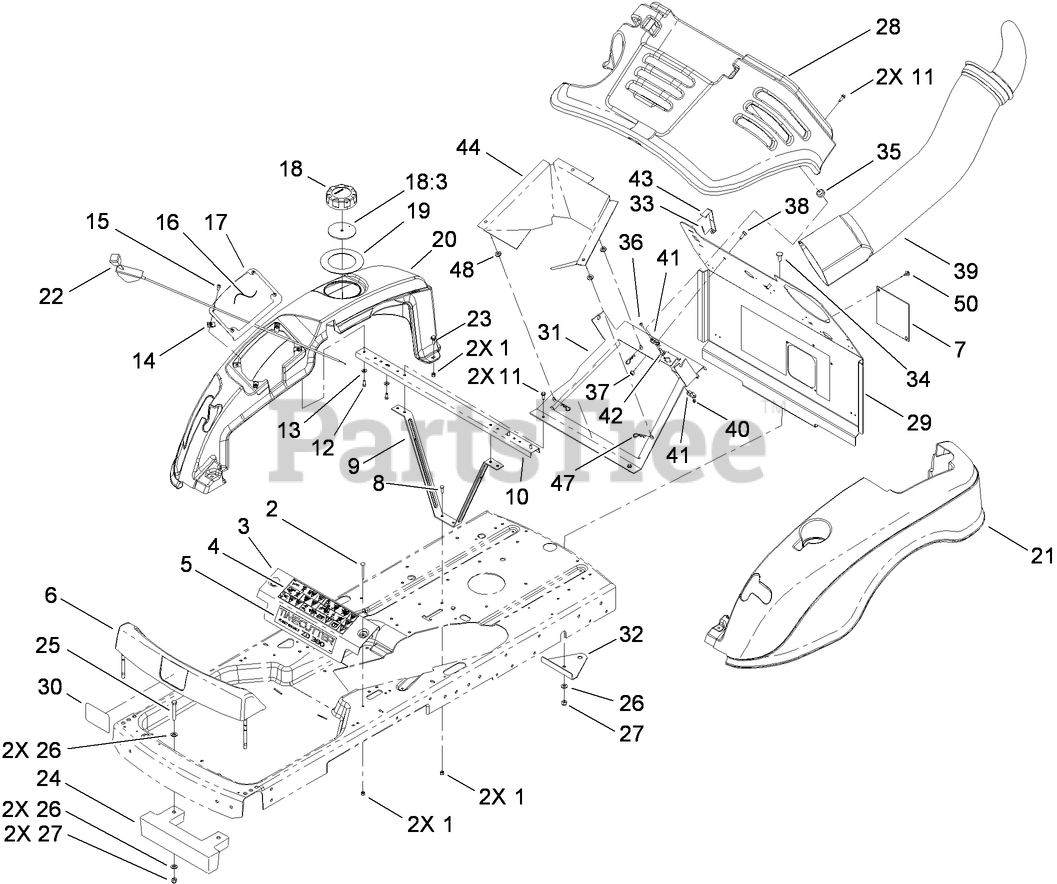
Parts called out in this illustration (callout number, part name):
1	NUT-LOCK, NI
2	SCREW-CARR
3	BRACKET-SUPPORT, FRONT
4	DECAL-DANGER
6	FOOTREST ASM
7	ACCESS DOOR ASM
8	SCREW-HH
9	BRACE ASM
10	CHANNEL-CROSS
11	SCREW-HWH, THREAD ROLL
12	SCREW-PLASTITE
13	WASHER-FLAT
15	SCREW-PRH
16	DECAL-CONTROL
17	PANEL-CONTROL
18	GAS CAP ASM
18:3	GASKET-CAP, GAS
19	SEAL-RUBBER
20	COVER-SIDE, RH
21	COVER-SIDE, LH
22	CABLE-THROTTLE
23	SCREW-SHOULDER
24	WEIGHT-BAGGER
25	SCREW-HH
26	WASHER-FLAT
27	NUT-LOCK, NI
28	COVER-ENGINE
29	SHIELD-HEAT, BAG
31	OFFSET HINGE ASM
32	HITCH-TRAILER
33	PIN-COTTER
34	SCREW-CARR
35	GROMMET
36	SCREW-HSBH
37	NUT-LOCK, NI
38	SCREW-HH
39	TUBE-DISCHARGE
40	NUT-LOCK, NI
42	PIN-HOOD
43	TAB-SWITCH
44	DUCT-FAN, ENGINE
47	PIN-HAIR
48	WASHER-RUBBER
50	SCREW-HHFTF
